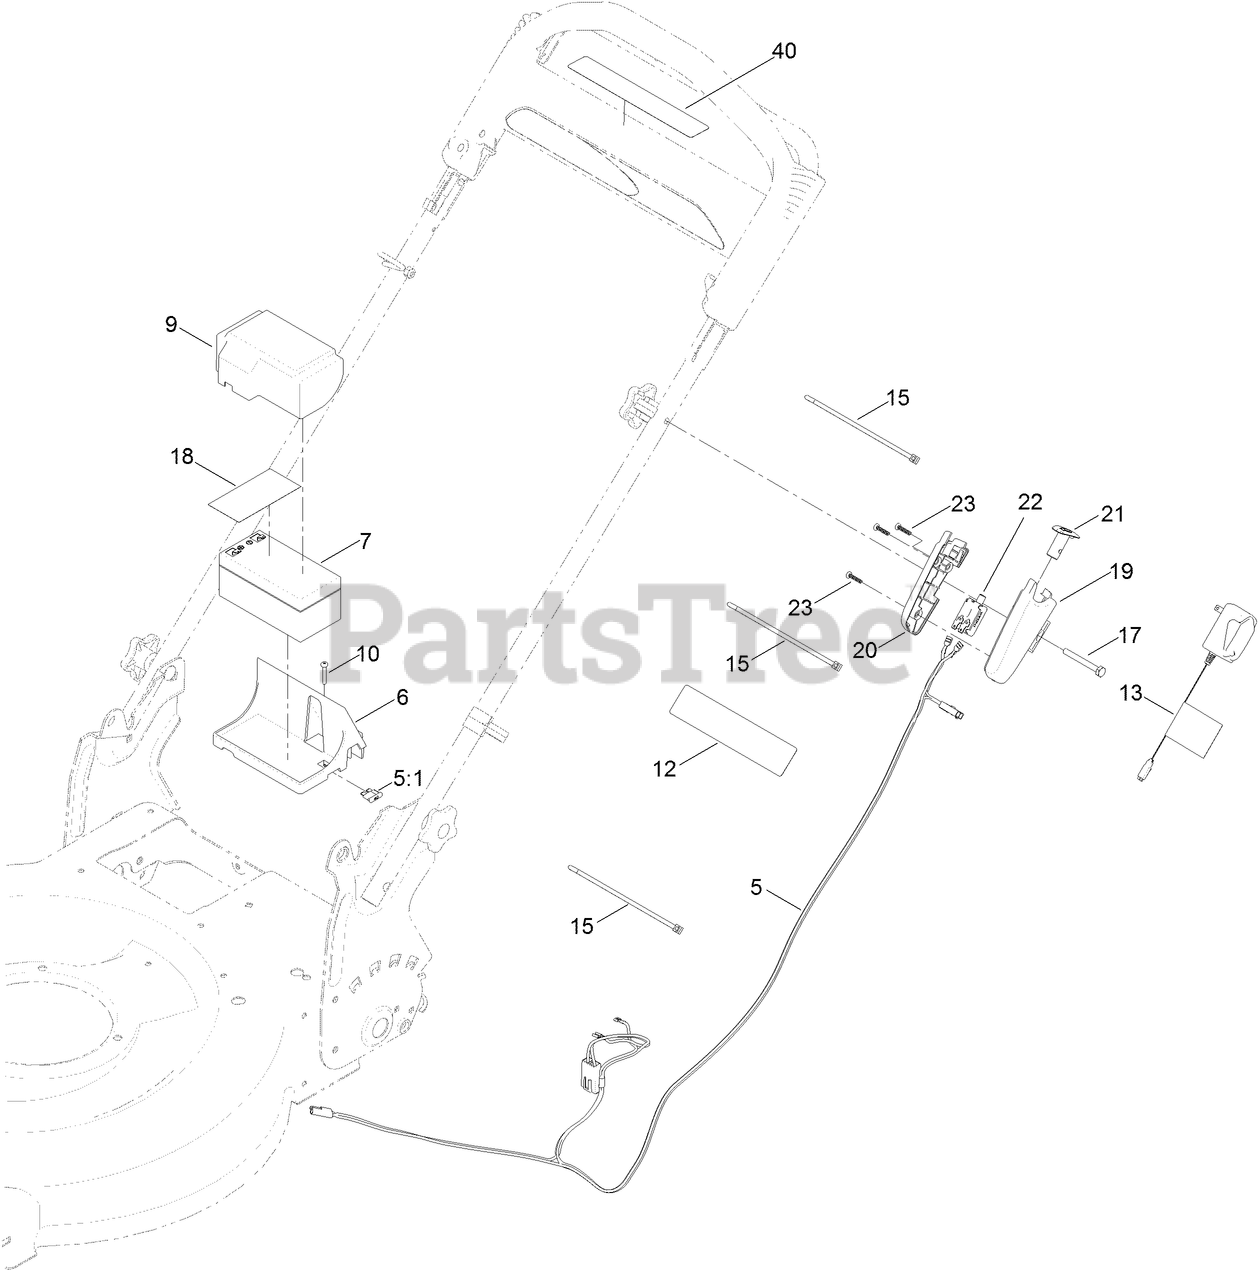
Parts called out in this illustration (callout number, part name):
5	HARNESS-WIRE
5:1	FUSE-40 AMP
6	TRAY-BATTERY
7	BATTERY-WET
9	COVER-BATTERY
10	SCREW-PPH, PLASTITE
12	DECAL-WARNING
15	TIE-CABLE
17	SCREW-HH
18	DECAL-TERMINAL, BATTERY
19	HOUSING-SWITCH, LH
20	HOUSING-SWITCH, RH
21	BUTTON-SWITCH
22	SWITCH-PUSH BUTTON
23	SCREW-PPH
40	DECAL-BUTTON, PUSH
